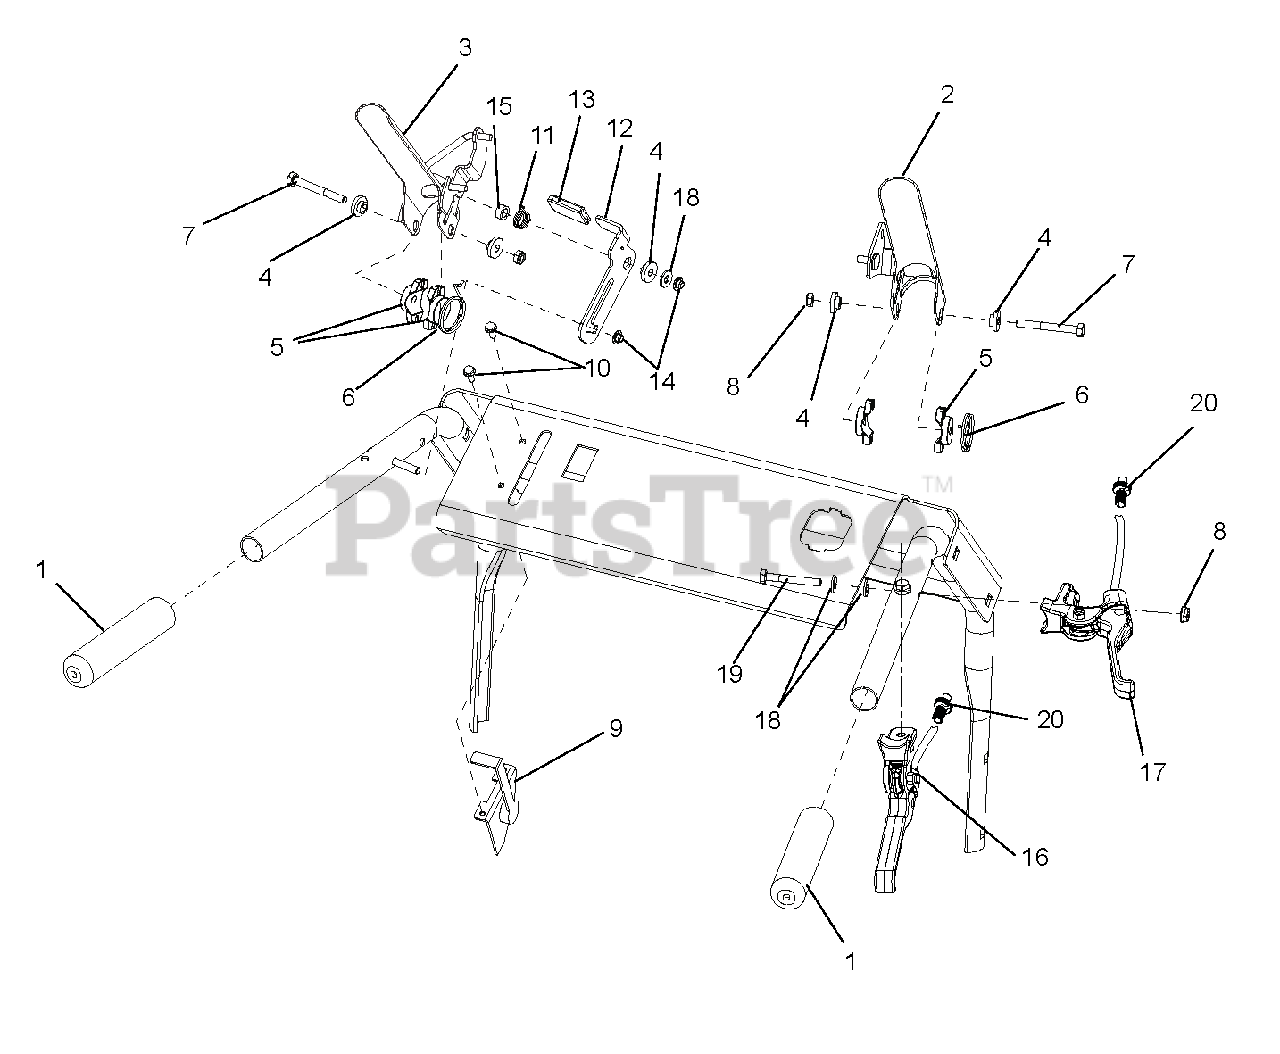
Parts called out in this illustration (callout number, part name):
1	HANDLE GRIP
2	PADDLE, P-BRAKE
3	HANDLEBAR, CE LH (WELDMENT)
4	BSHG, FLG .266X.42X.150 PM
5	SPACER, HANDLEBAR
6	SPRING, TORSION
7	@BLT-HEX .25-20X2.25 GR5 YWZC
8	NUT-JAM-NYL .250-20 W/INSERTYZ
9	CABLE, WAW THROTTLE
10	@SCR-TAP 10-24X.50 HWH TR YWZC
11	SG-TORS
12	BRKT-LEVER, INTERLOCK
13	GRIP, THUMB LATCH
14	PUSH NUT, .25
15	TUBE-SPACER .33X.50X.XX
16	CONTROL-LEVER W/CABLE FORWARD
17	CONTROL-LEVER W/CABLE REVERSE
18	@WSHR-FL-STL.281X.62X.065 YWZC
19	@BLT-HEX .25-20X2.00 GR5 YWZC
20	CABLE ADJUSTER, STEEL
